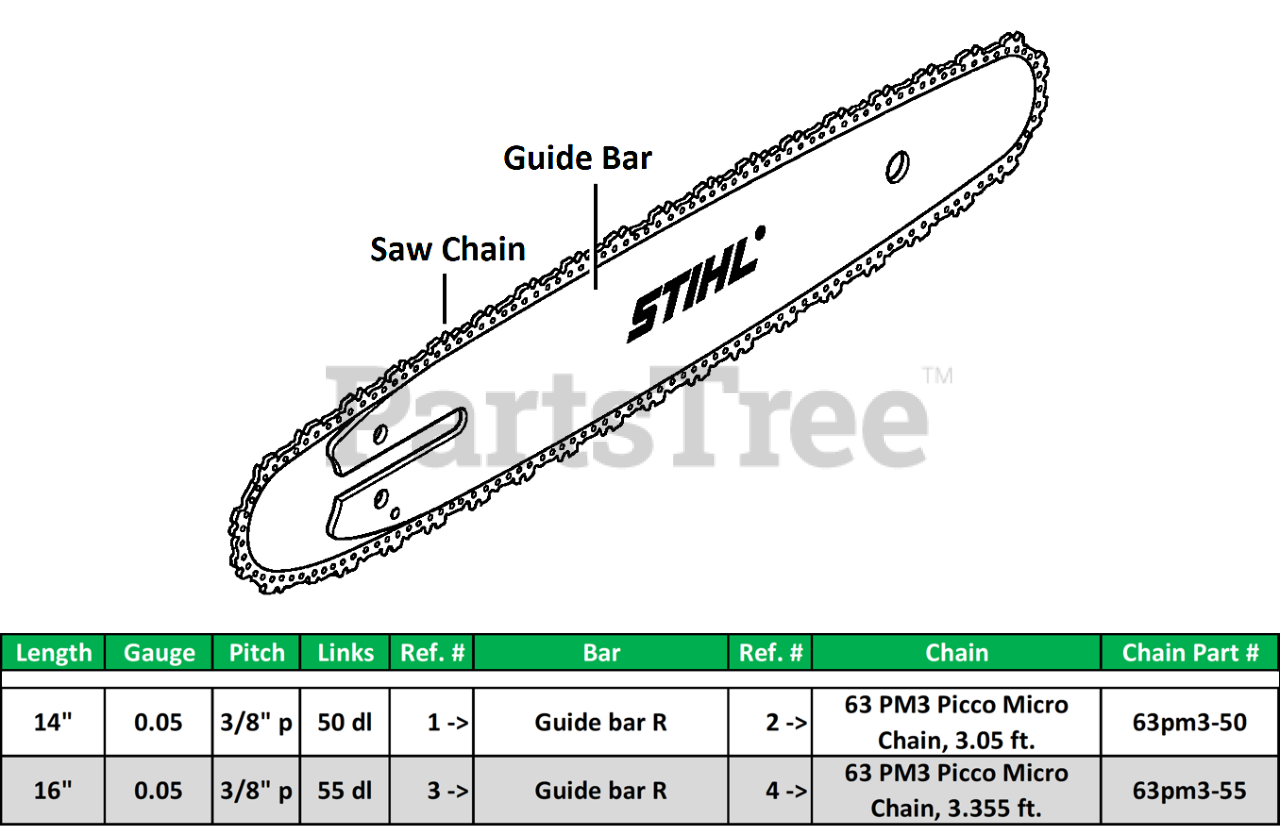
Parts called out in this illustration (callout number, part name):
1	Guide bar R 35cm/14" 1,3mm/0.050" 3/8" P
2	63 PM3 Picco Micro Chain, 3.05 ft.
3	Guide bar R 40cm/16" 1,3mm/0.050" 3/8" P
4	63 PM3 Picco Micro Chain, 3.355 ft.
